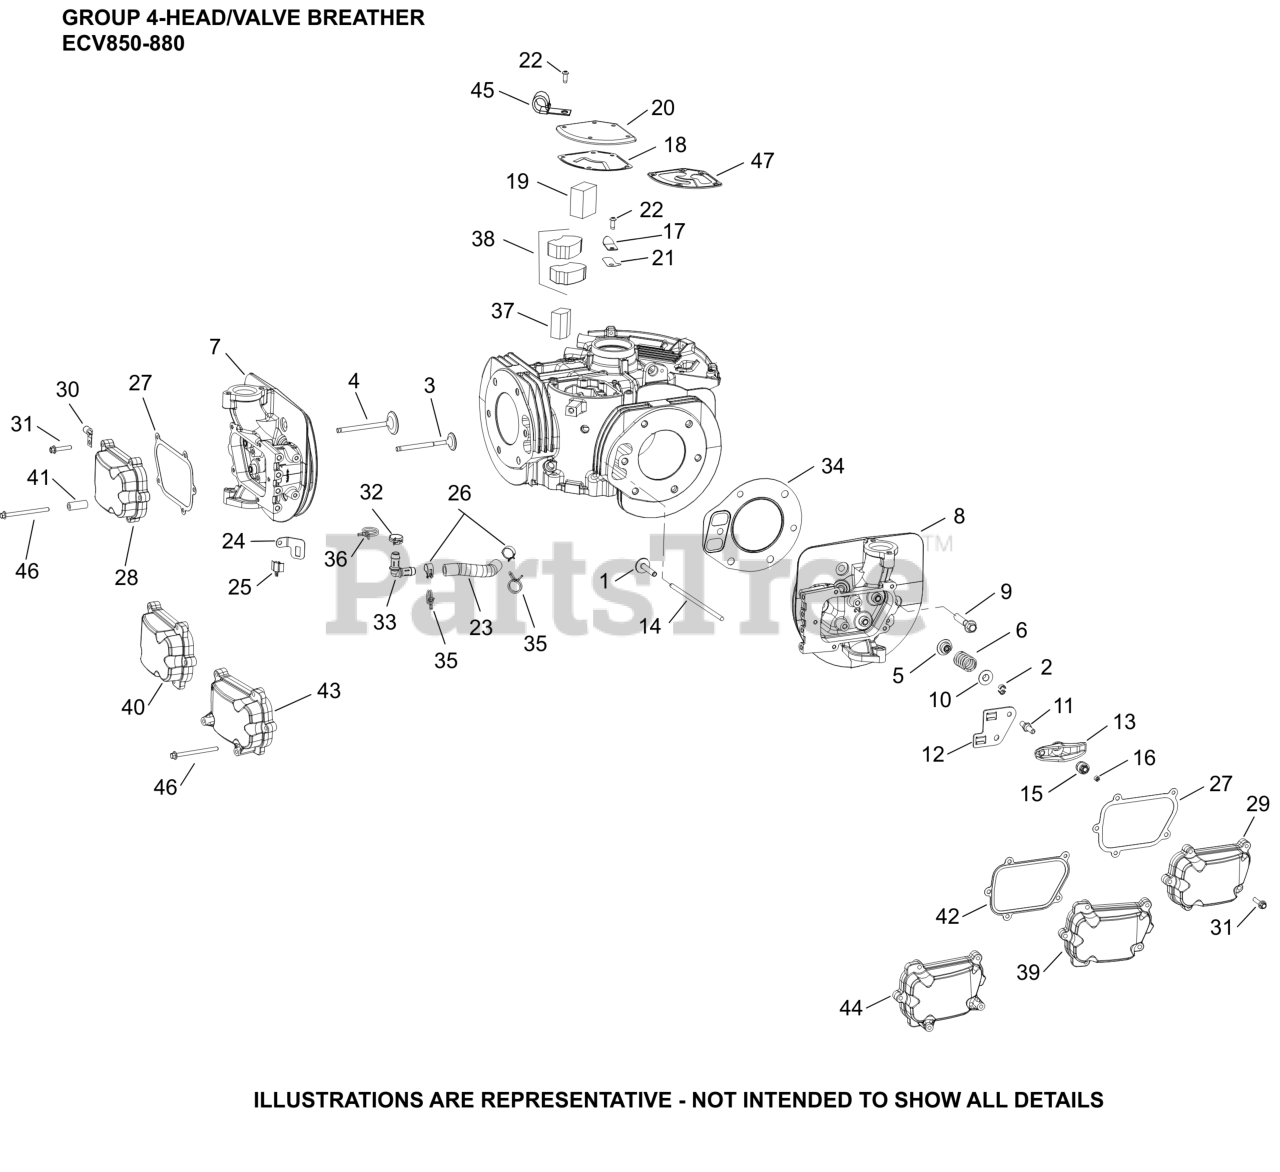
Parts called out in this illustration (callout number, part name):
1	TAPPET, COATED
2	KIT, RETAINER
3	VALVE, EXHAUST
4	VALVE, INTAKE
5	SEAL, VALVE STEM
7	CABEZA CILINDRO NO.1/KIT,CYLINDER HEAD#1
8	KIT,CYLINDER HEAD#2
9	SCREW, HEAD
10	CAP, VALVE SPRING
11	STUD, ROCKER-(#1907206S)
12	PLATE, PUSHROD GUIDE
13	ARM, ROCKER
14	ROD, PUSH
15	PIVOT, ROCKER ARM
16	SCREW, SET
17	RETAINER, REED
20	COVER, BREATHER
21	REED, BREATHER
22	SCREW, BUTTON HEAD
23	HOSE, BREATHER
24	BRACKET, OXYGEN SENSOR
25	CLIP, O2 SENSOR
31	SCREW, FLG M6X1.0X80
33	FITTING, 90 DEGREE
34	KIT, HEAD GASKET (824)
35	CLAMP, HOSE
36	CLAMP, HOSE
37	FILTER, BREATHER MEDIA (LOWER HALF)
38	FILTER, BREATHER MEDIA (UPPER HALF)
42	GASKET, VALVE COVER
43	KIT, VALVE HEAD COVER #1
44	KIT, VALVE HEAD COVER #2
45	CLIP, CABLE (KM)
47	GASKET, BREATHER
NI	SPRING, VALVE
